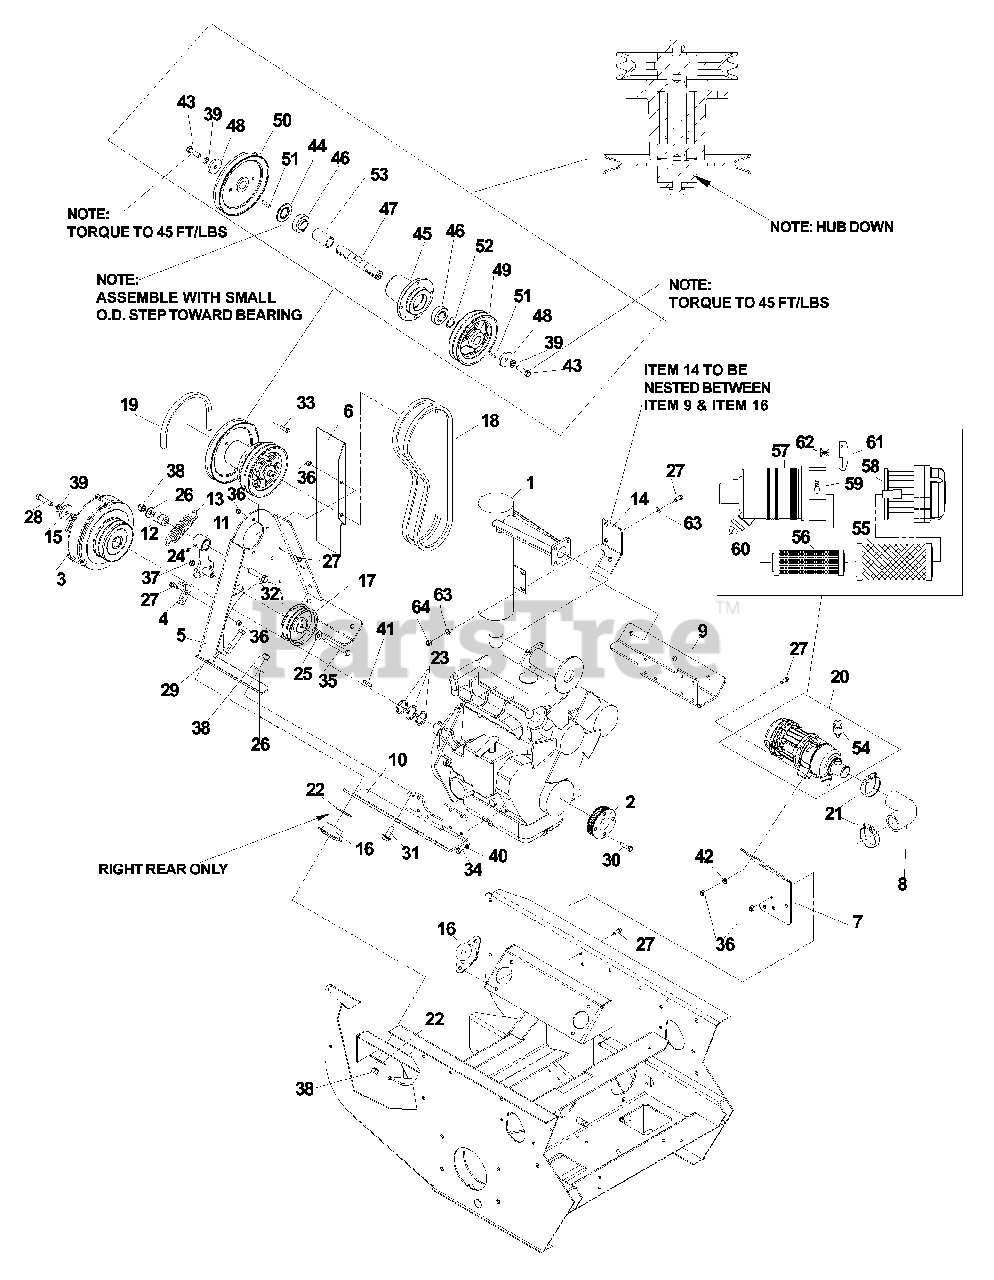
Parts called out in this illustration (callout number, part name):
1	Muffler
2	Sheave, engine
3	Clutch
4	Restraint
5	Jack mount
6	Shield, heat
7	Bracket, air filter
9	Engine mount, left
10	Engine mount, right
14	Muffler mount
15	Washer, heavy
16	Isolator mount, engine
17	Idler
18	Belt, primary (matched set only)
19	Belt, mule
20	Air filter assembly
22	Isolator washer
23	Bushing, machine, 1 1/8 x 10 ga.
24	Zerk
25	Washer, 3/8,SAE
26	Washer, 1/2
27	Bolt, 5/16-18 x 3/4
28	Bolt, 7/16- 20 x 2 1/2
29	Bolt, 1/2-13 x 2 3/4
30	Bolt, M8-1.25 x 35
31	Bolt, 1/2-13 x 1 1/4, serrated head
32	Bolt, 1/2-13 x 2 1/2
33	Bolt, 5/16-18 x 1
34	Bolt, M8 x 1.25 x 20
35	Bolt, 3/8-16 x 3 1/2
36	Nut, 5/16-18, nyloc
37	Nut, 3/8-16, nyloc
38	Nut, 1/2-13, nyloc
39	Lockwasher, 7/16
40	Lockwasher, 5/16
41	Key, 1/4 sq. x 1 7/8
42	Washer, 5/16
43	Bolt, 7/16-20 x 1 1/2
44	Combo spacer
46	Bearing
48	Washer, heavy
51	Key, 1/4" sq. x 1 1/8"
52	Machine bushing, 18 ga
54	Indicator, air filter
55	Air filter
56	Safety element
58	Precleaner assembly
59	Mounting bracket
63	Washer, 3/8, spring
64	Nut, 5/16-18
